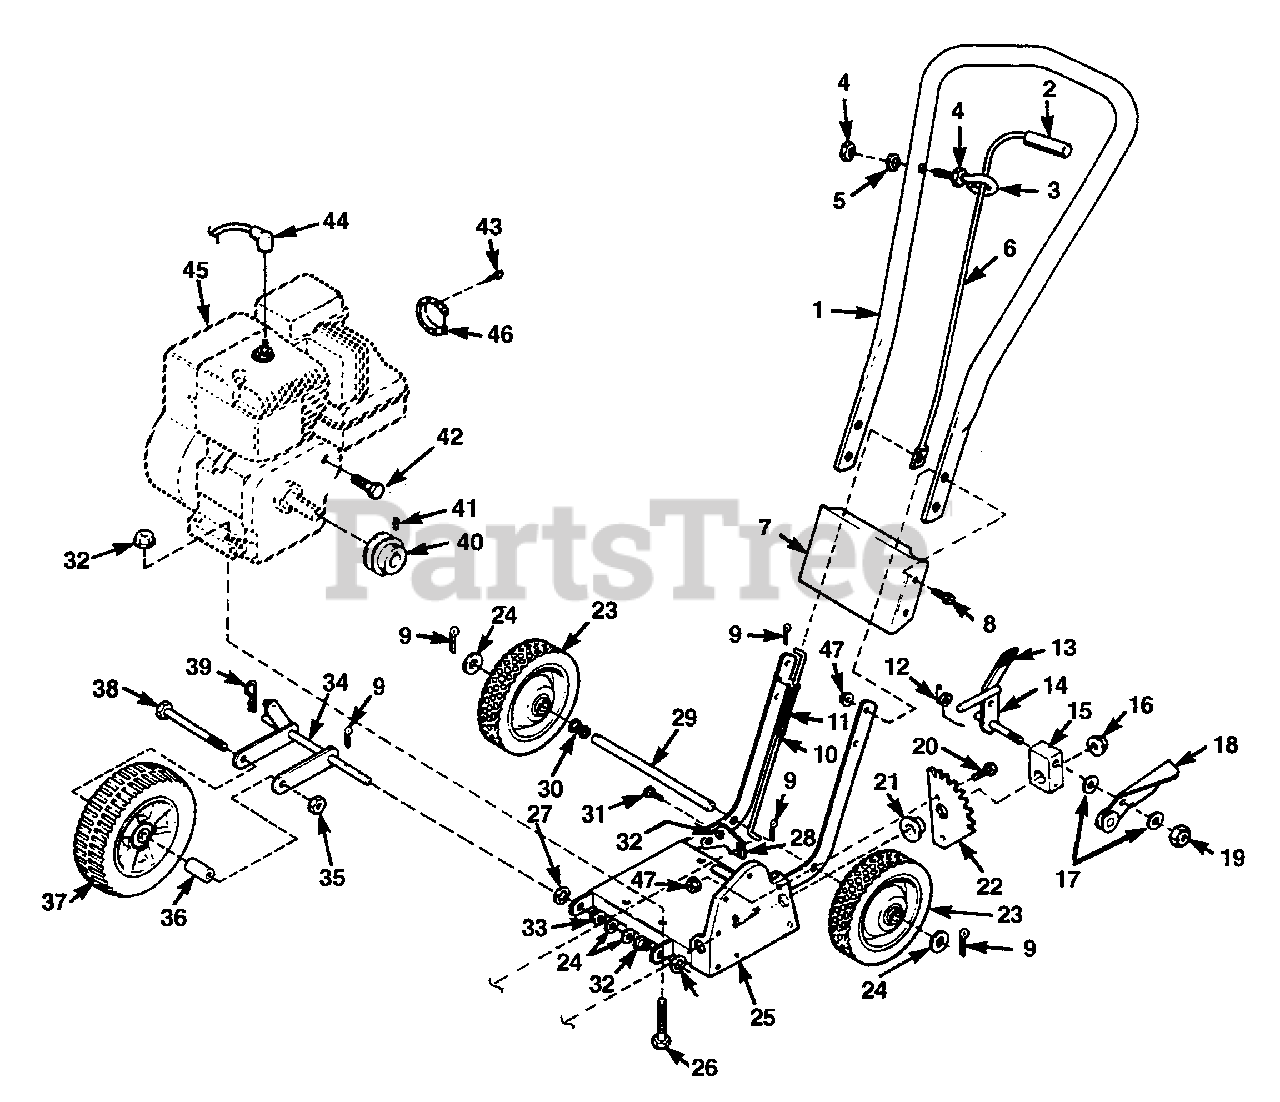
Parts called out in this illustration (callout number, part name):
1	HANDLE-Edger
2	GRIP-Depth Control
4	NUT-Hex (1/4-20)
6	CONTROL-Depth
7	COVER-Handle
8	SCREW-Sems (1/4-20 X 1")
9	PIN-Cotter
10	ROD-Lower Depth Control
11	SPRING-Depth Control
12	SPRING-Angle Adjusting
13	GRIP-Angle Adjusting
14	LEVER-Angle Adjusting
15	CLAMP-Angle
16	NUT-Hex
17	WASHER-Flat
18	LEVER-Clutch
19	NUT
20	SCREW-Sems Hex Hd.
21	BUSHING-Nylon (3/4")
22	COMB-Angle Adjusting
23	WHEEL & TIRE
24	WASHER-Flat
25	FRAME-Main
26	SCREW-Cap Hex Hd.
27	RETAINER-Bushing
28	BRACKET-Depth Control
29	AXLE-Rear
30	SPRING-Axle
31	SCREW (5/16-18 X 1")
32	NUT-Hex w/Washer
33	BUSHING-Nylon
34	BRACKET-Front Wheel
35	NUT-Hex
36	SPACER-Axle
37	WHEEL-Front
38	SCREW (1/2-13 X 4")
39	PIN-Cotter Hair
40	PULLEY-Engine
41	SCREW-Set (5/16-18 X 3/8")
42	SCREW (5/16-24 X 1/2")
43	SCREW-Thread Rolling (8-32 X 1/2")
44	TERMINAL-Hi-Tension
45	ENGINE
46	DEFLECTOR
47	NUT (1/4-20)
